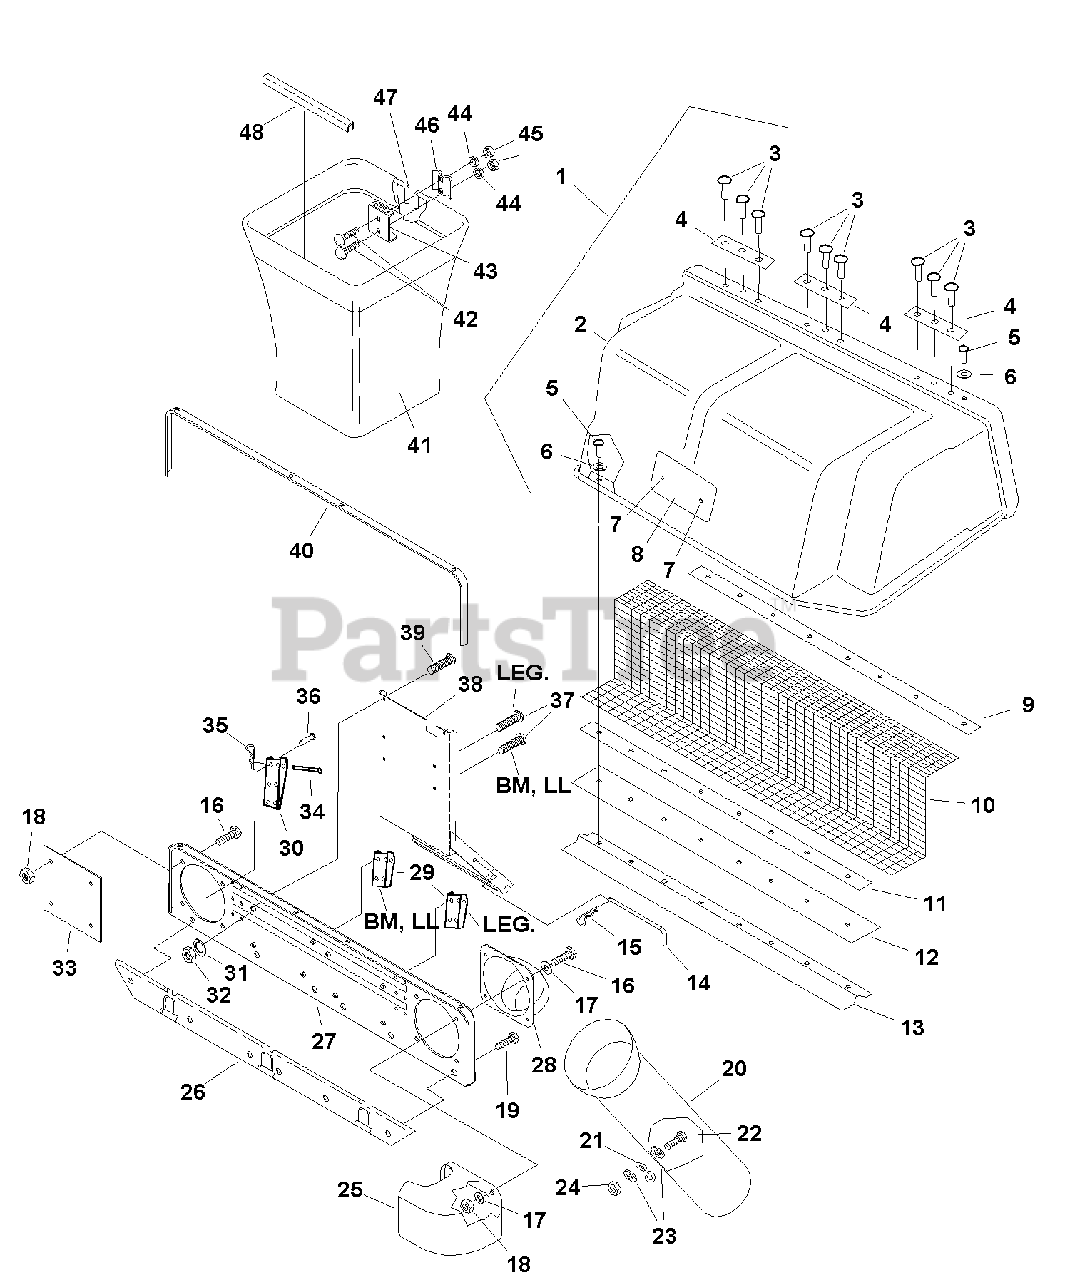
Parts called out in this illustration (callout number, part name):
1	COVER & SCREEN ASSEMBLY (Inc. Ref. No. 2,3,4,5,6,9,10,11,12,13)
2	COVER, GRASS CATCHER
4	PLATE ASSSEMBLY
7	CLIP, Canoe
8	DECAL, Saftey
11	CLAMP, Seal
13	ANGLE, Screen
16	CAPSCREW, Hex Head, 5/16-18 x 1
17	WASHER, 5/16
18	LOCKNUT, 5/16-18
19	CAPSCREW, Taptite, 1/4-20 x 1/2
22	CAPSCREW, Hex Head 1/4-20 x 1-1/4
23	WASHER, 1/4
24	LOCKNUT, 1/4-20
26	BRACKET ASSEMBLY
27	PLATE ASSEMBLY
31	LOCKWASHER, 5/16
32	NUT, 5/16-18
34	PIN, 3/8 x 2-3/4
35	PIN, Hair
36	RIVET
37	CARRIAGE BOLT, 5/16-18 x 1-1/4
38	SUPPORT ASSSEMBLY
39	CARRIAGE BOLT, 5/16-18 x 3/4
42	CARRIAGE BOLT, 5/16-18 x 3/4
44	LOCKWASHER, 5/16
45	NUT, 5/16-18
47	HOOP, Basket Frame
